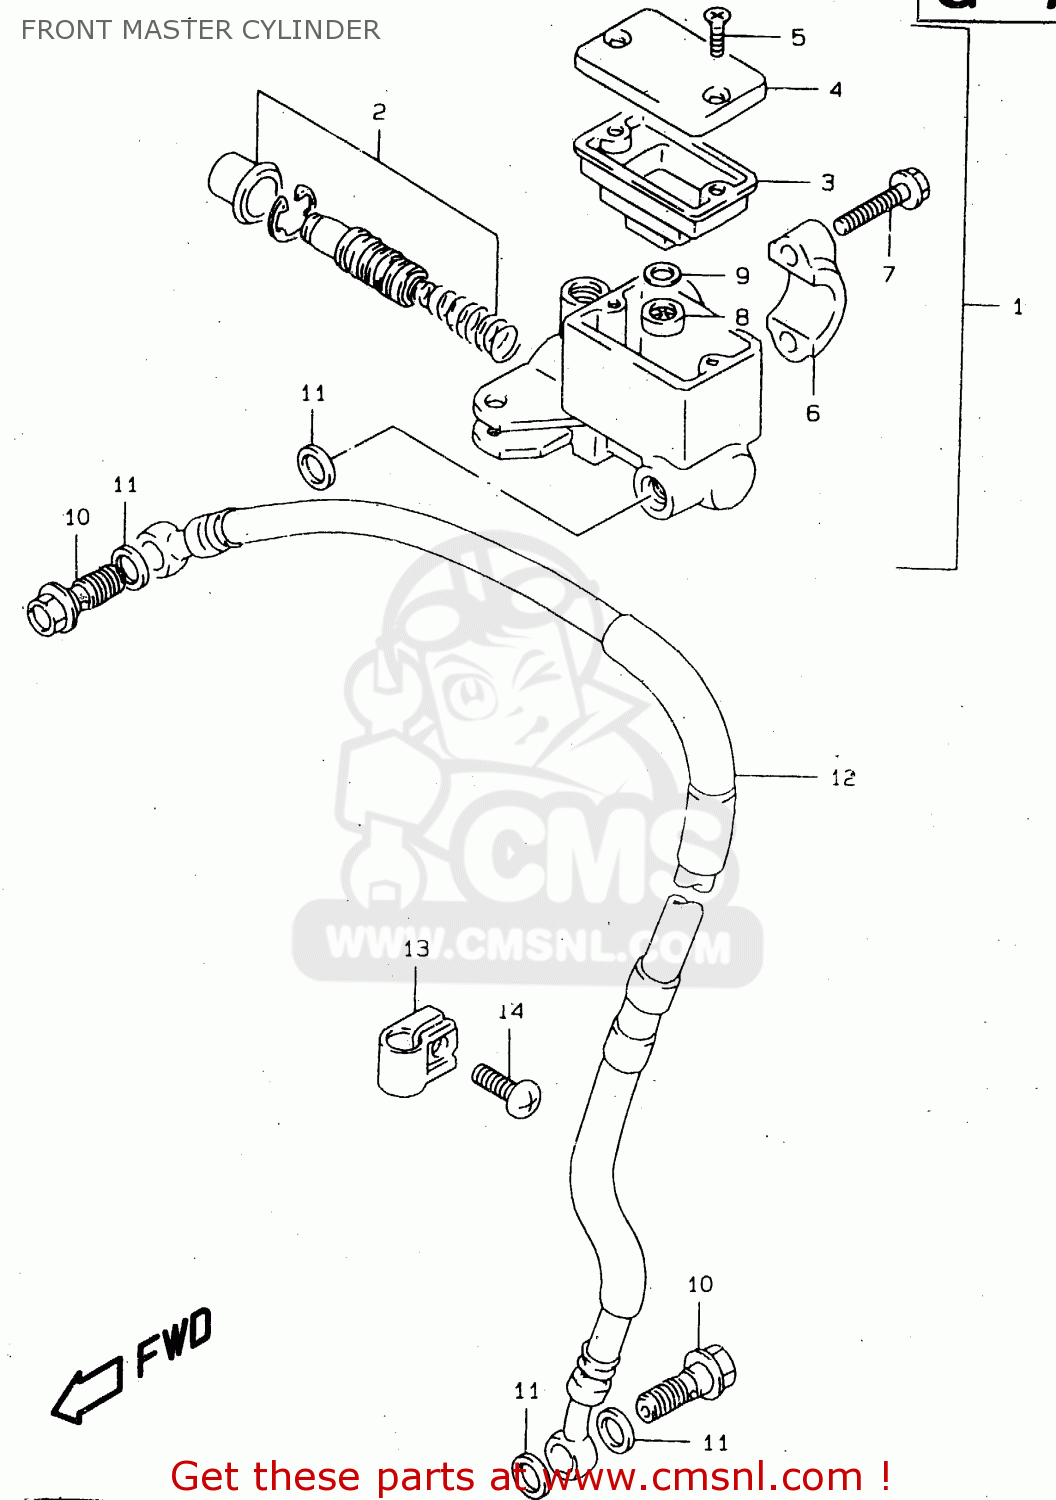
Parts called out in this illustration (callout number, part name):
1	CYLINDER ASSEMBLY,FRONT MASTER
2	PISTON/CUP SET
3	DIAPHRAGM
4	CAP
5	SCREW
6	HOLDER
7	BOLT(6X25)
8	SEPERATOR
9	PLATE
10	BOLT UNION
11	WASHER(10X15X1.5)
12	HOSE COMP,FRONT BRAKE
13	CLAMP,BRAKE HOSE
14	SCREW
